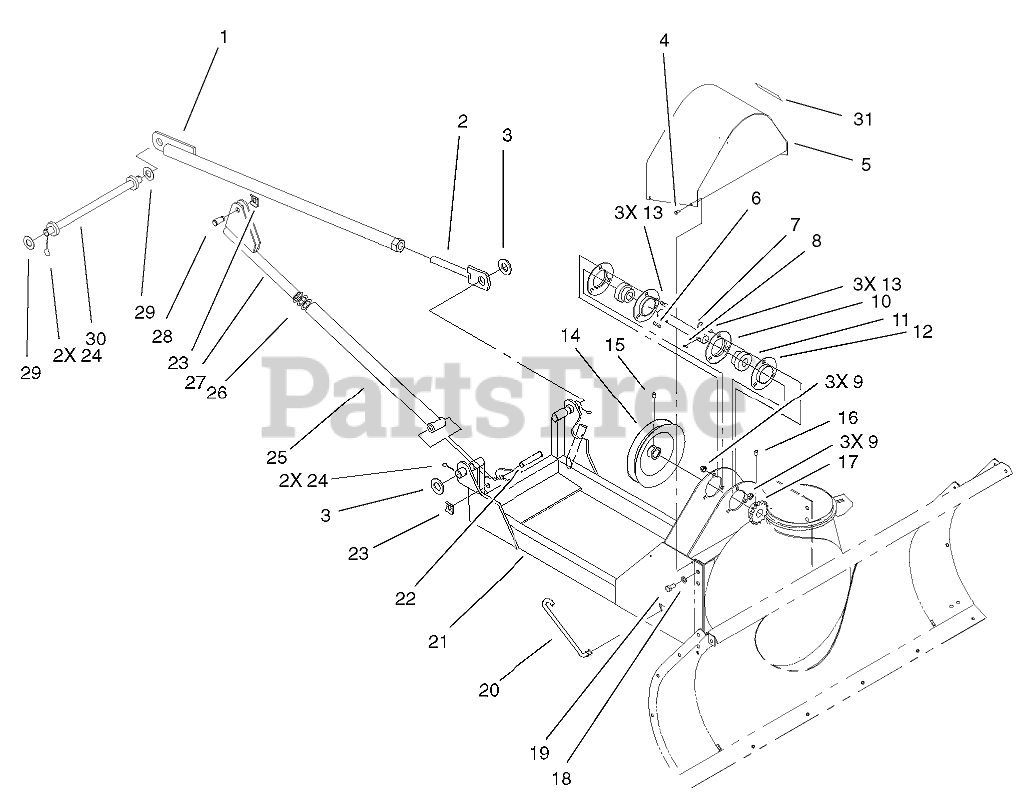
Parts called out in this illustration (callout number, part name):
1	BRACE ASM
2	ADJUSTER ASM
3	WASHER-FLAT
4	SCREW-TAPTITE
5	PULLEY COVER ASM
6	KEY
7	SHAFT - JACK
8	KEY-HI PRO
9	NUT-LOCK, NI
10	FLANGE-RELUBE
11	BEARING AND COLLAR
12	Flange
13	BOLT-CARR
14	PULLEY-DRIVE
15	SCREW-SQH
16	SCREW-SET
17	SPROCKET-15 T
18	WASHER-LOCK
19	SCREW-HH
20	LINK-SPRING TENSION
21	FRAME ASM
22	PIN-CLEVIS
23	CLIP-PIN
24	PIN-COTTER, HAIR
25	ROD-LIFT
26	WASHER-FLAT
28	PIN-CLEVIS
29	WASHER-FLAT
30	LINK ASM
31	DECAL-IMPORTANT
